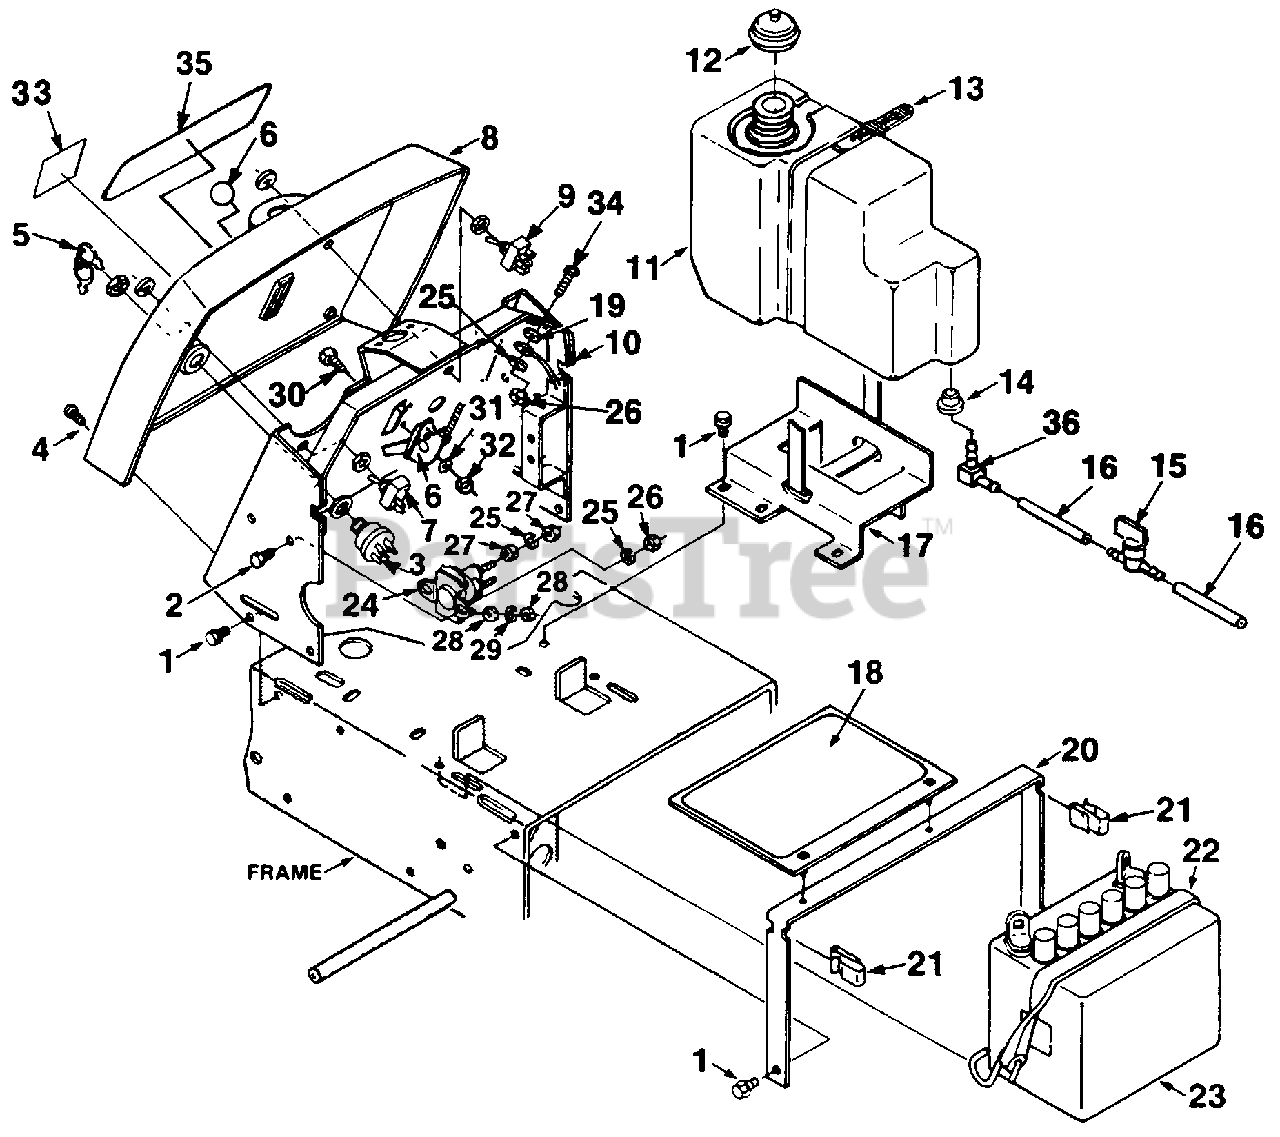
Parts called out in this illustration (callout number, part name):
1	BOLT- (1/4-14 x .44)
2	SCREW- Hex (1/4-20 x 1/2")
3	SWITCH- Key
4	SCREW- (#10 x 3/4")
6	CONTROL- Throttle
7	SWITCH- Headlight
8	PANEL- Dash
9	SWITCH- PTO
10	CONTROL TOWER ASSY.
12	CAP- Fuel
13	STRAP- Gas tank
15	VALVE- Shut off
16	TUBING- Rubber (fuel line)
18	DECAL- Battery
19	WASHER- External tooth (1/4")
22	STRAP- Hold down
25	WASHER- Lock (1/4")
26	NUT- Hex (1/4-20)
27	NUT- (1/4-20)
28	NUT- Hex (8-32)
29	WASHER- Lock (#8)
30	SCREW- (10-24 x 1/2")
31	WASHER- Plain (1/4")
32	NUT- Hex Centerlock (10-24)
33	DECAL- Throttle
34	BOLT- (1/4-20 x 7/8")
35	DECAL- Instruction
